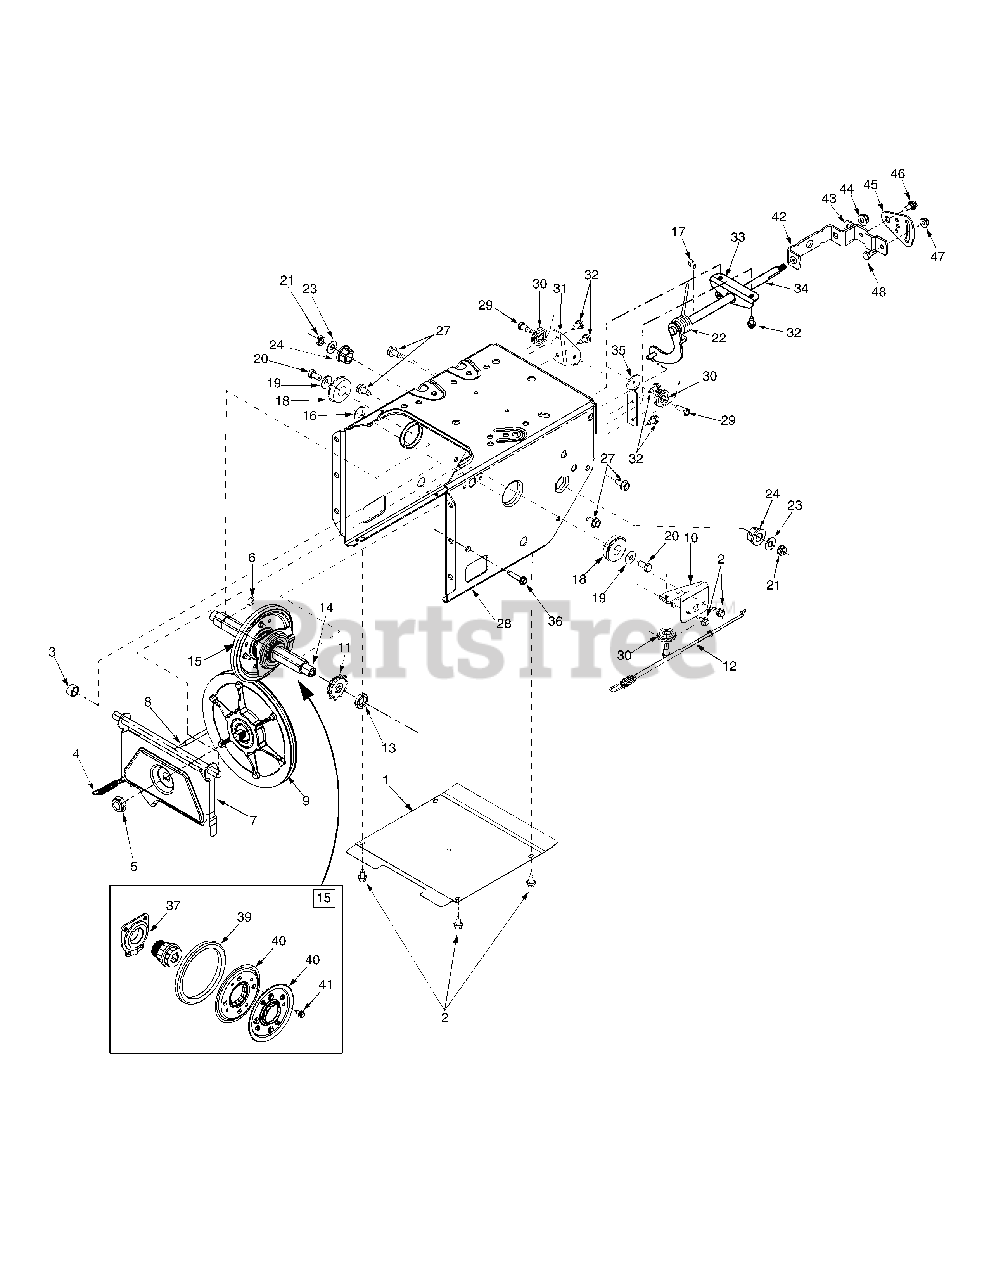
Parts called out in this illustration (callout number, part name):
3	Spacer .525 ID x .75
4	Extension Spring 3/8 OD x 2.50
5	Flange Nut 5/8-18
6	Retaining Ring
9	Friction Wheel Disc Assembly
10	Front Support Guide Bracket
11	10T Sprocket #41 x .500
12	Auger Clutch Cable (w/Z fitting)
13	Spacer .625 ID x 1.0 OD x .23
14	Hex Track Shaft
15	Friction Wheel Assembly
16	Speed Nut
18	Ball Bearing w/snap ring
19	Cupped Washer .345 ID x .88 OD x .060
20	Hex L-Bolt 5/16-18 X .62
21	Hex Nut 3/8-24
22	Torsion Spring
23	Flat Washer .406 ID x .875 OD x .059
24	Hex Flange Bearing
27	Hex TT Screw 5/16-18 x .75
29	Hex Shld.Screw.1/4-28 x .375
30	Cable Guide Roller
31	Drive Cable Guide Bracket
32	Hex Wash S-Tapp Screw 1/4-20 x .50
34	Shift Rod Assembly
35	Auger Clutch Cable Guide Bracket
36	Hex Bolt 1/4-20 x 1.00
37	Friction Wheel Bearing Assembly
39	Friction Wheel Rubber
40	Friction Plate
41	Hex Wash. Hd. TT Screw. 1/4-14 x .625
42	Speed Selector Shift Bracket
43	Flat Washer
44	Flange Locknut 5/16-18 Gr. F, Nylon
45	Speed Selector Pivot Bracket
46	Shoulder Screw 1/4-20
47	Hex L-Flanged Nut 1/4-20 Gr. F Nylon
48	Hex Bolt 1/4-20 x .62 Gr. 5
